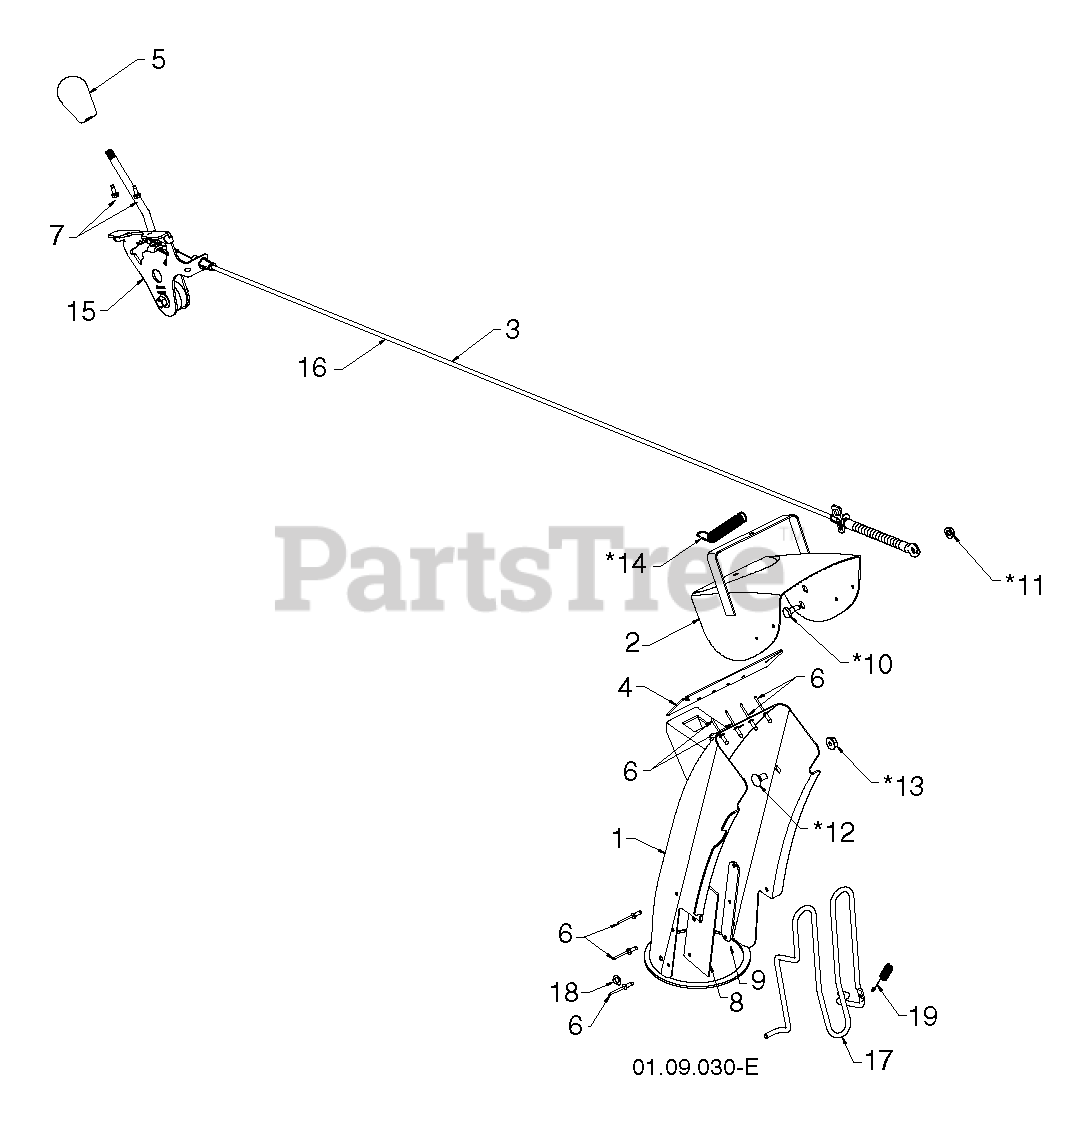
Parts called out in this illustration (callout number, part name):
1	RP_CHUTE.WELDMENT.SNOW.ORANGE
2	DEFLECTOR.WELDMENT.PNT.ORANGE
3	CONTROL.ASM.DEFLEC.BLK.BOWDEN
4	SEAL.DEFLECTOR
5	KNOB.OVERMOLD.DS.HUSQVARNA/BLK
6	RIVET BLIND
8	SHIELD.SNOW.CHUTE
9	STRAP.SHEILD.RETAINER
10	BOLT, SHOULDER
11	NUT.HEX.FLANGE.1/4
12	BOLT
13	NUT.LOCK.5/16-18
14	SPRING.DEFLECTOR.REM.CHUTE
15	RP CNTRL.HEAD.ASSEM.DEFLECTOR
16	RP CABLE.DEFLECTOR.BOWDEN
17	ROD.GUARD.CHUTE (2 2)
18	NUT
19	SPRING.CHUTE.GUARD
